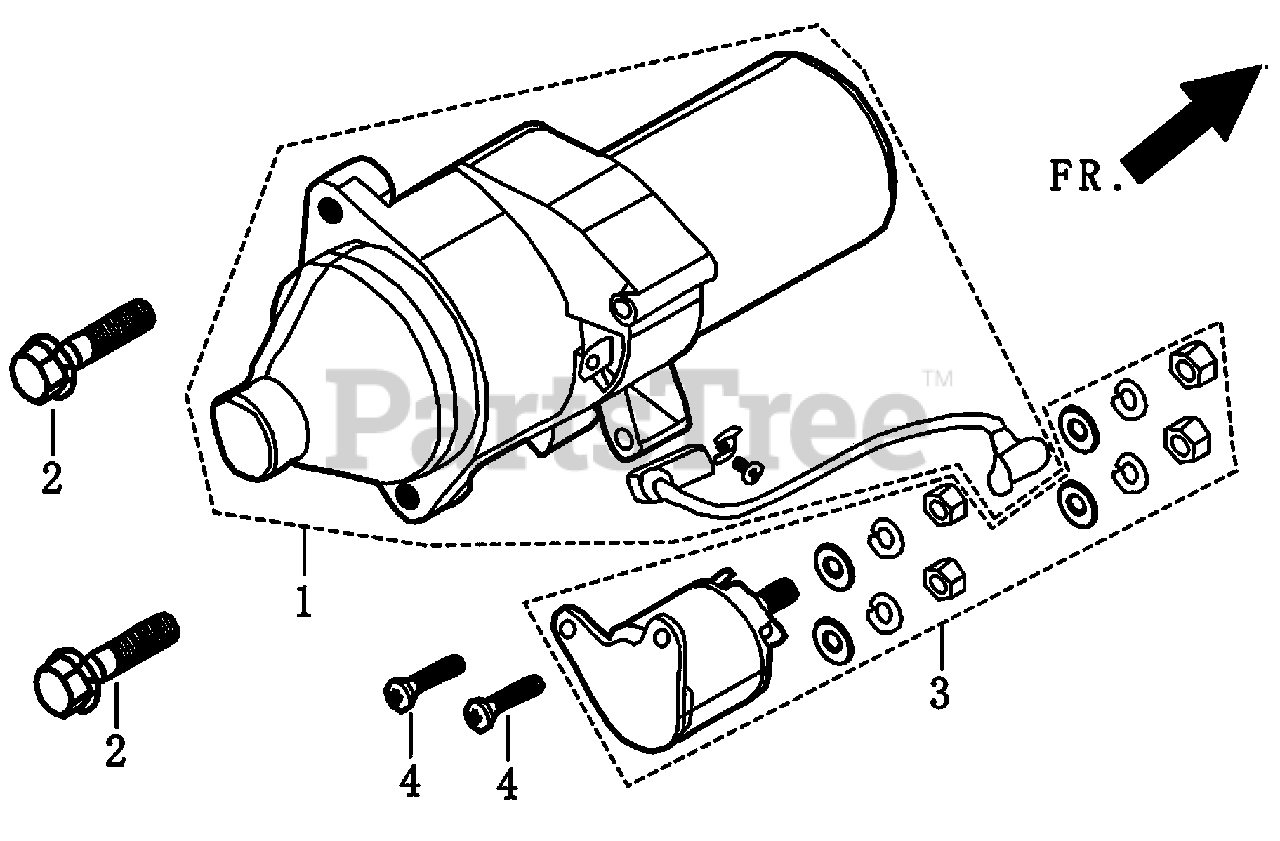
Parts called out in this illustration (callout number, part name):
1	MOTOR, STARTING
3	RELAY, STARTING
4	SCREW HHFC, M5-0.8 X 16
